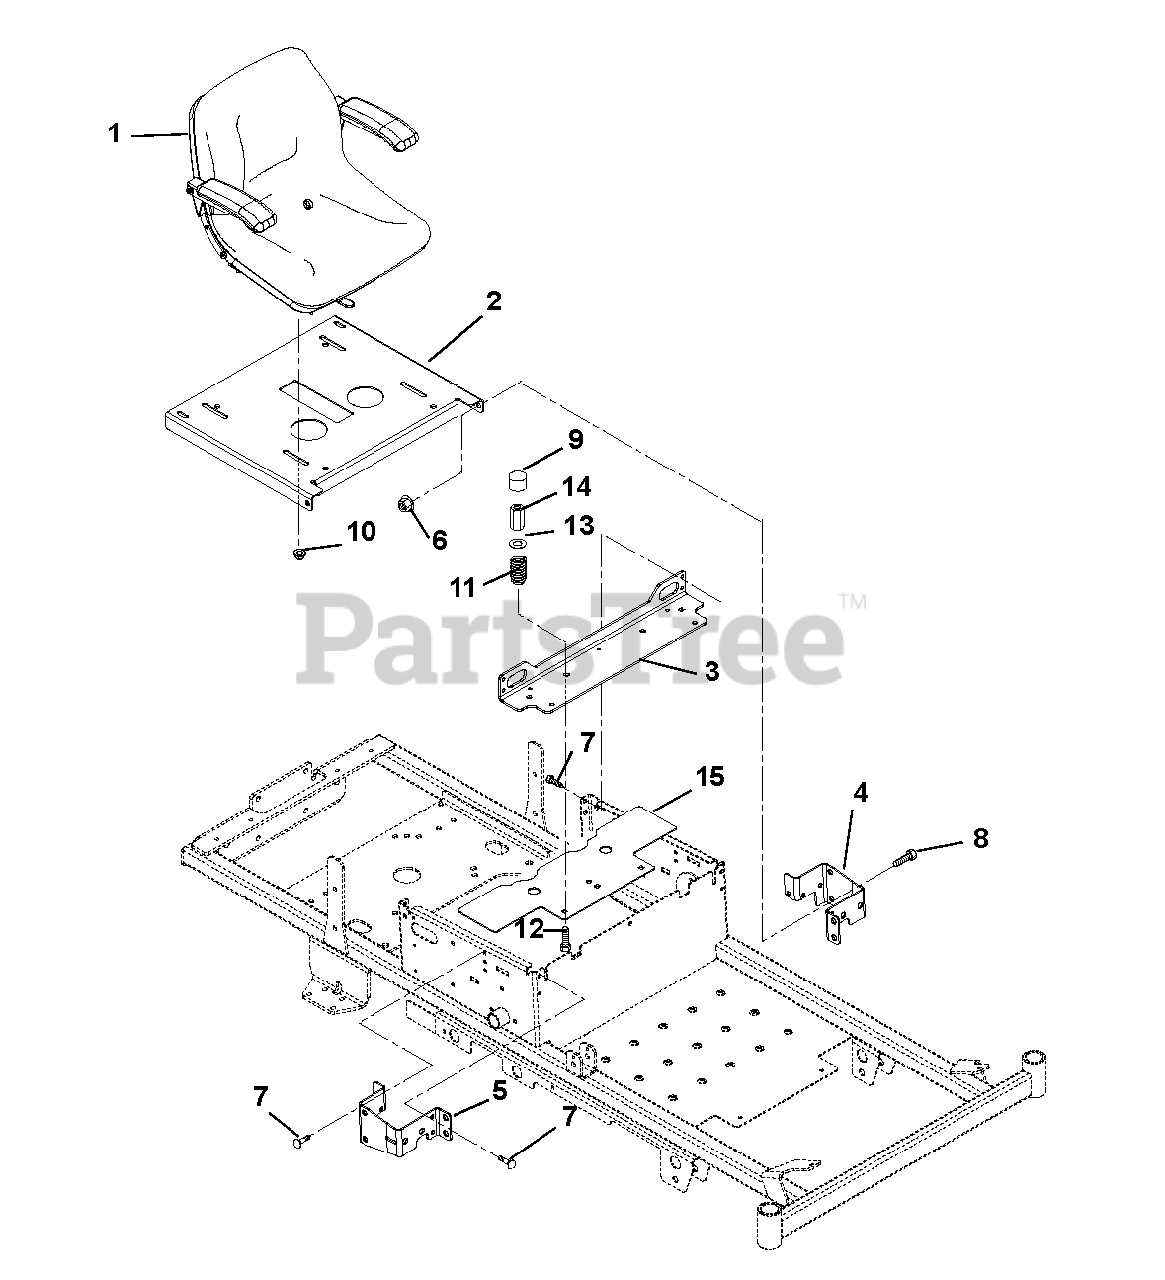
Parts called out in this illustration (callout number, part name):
1	Seat, 1008 W/ARMREST (SEATS INC)
2	Seat Plate
3	Bracket, Seat Spring
4	Bracket, Right Hand Steering Stop
5	Bracket, Left Hand Steering Stop
6	Nut, Locking Flange .38-16
7	Screw, Tapping .31-18 x .50
8	Bolt, Shoulder .375-16 x 1.50
10	Nut, .31-18 Nyloc Flange
11	Spring, Seat
12	Bolt, Round Head Square Neck .31-18 x 1.50 Grade 5
13	Washer, Flat Steel .328 x .87 x .179
14	Nut, Coupling 5/16-18 x 1 .75
15	Guard, Finger
